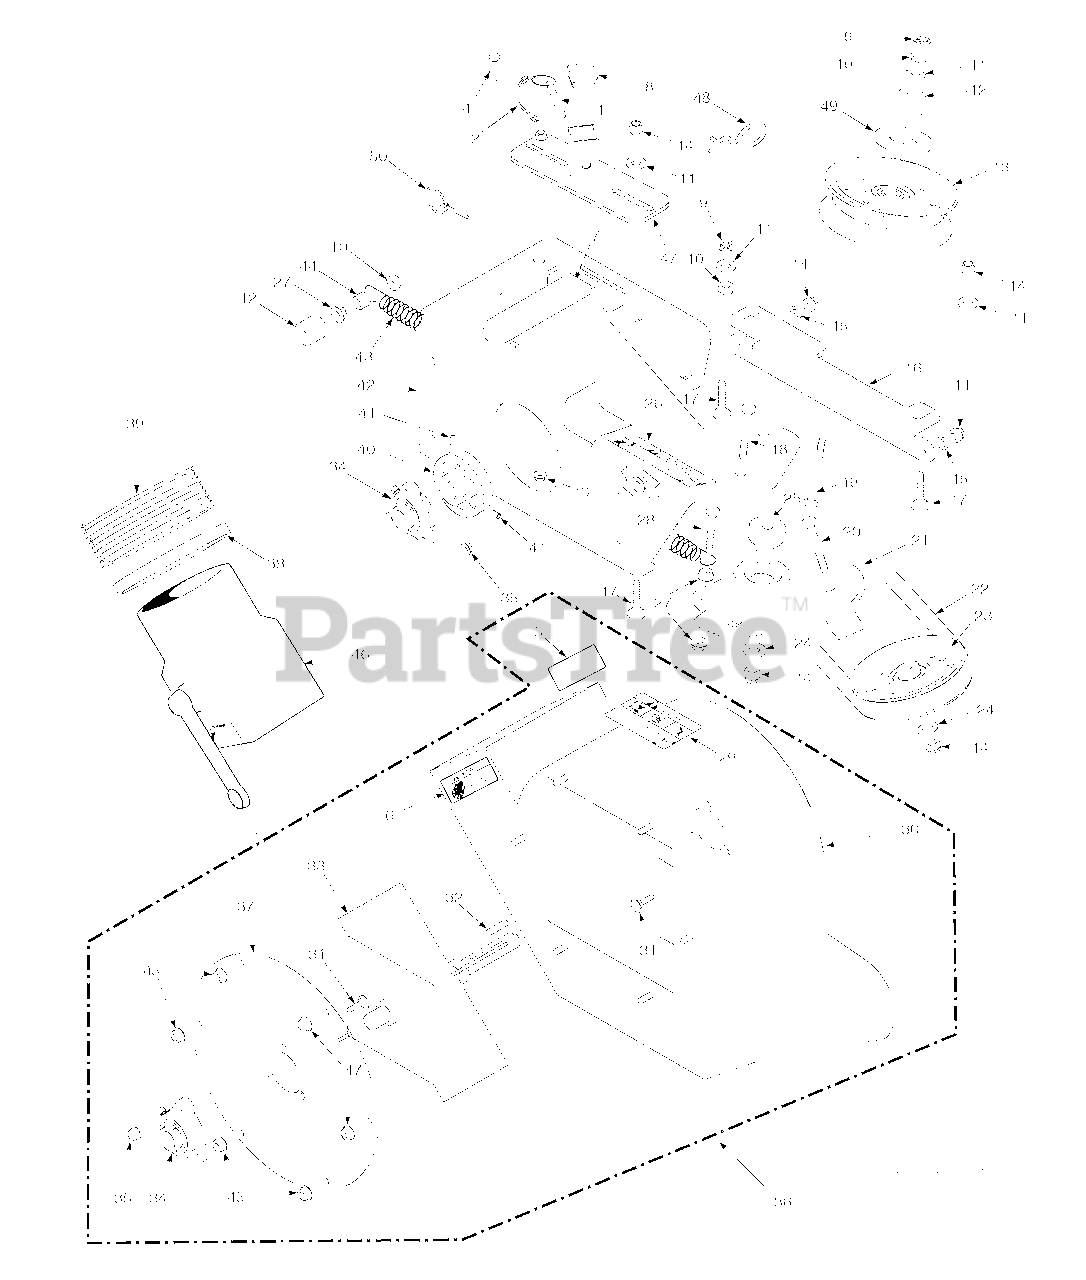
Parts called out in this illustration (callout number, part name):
1	Pin, Ring 2-1/4" Long
2	Lanyard, Deck Height Pin
3	Nut, Serr. Flange 1/4-20
4	Bolt, Hex Head 1/4-20 x 1-1/4"
5	Decal, Blower
6	Decal, Rotating Blower
7	Grip, Blower Lever
8	Cap, Square
9	Nut, Push On 3/8 Thread
10	Lock Nut, 3/8-16
11	Flatwasher, 3/8-.391 x .938 x .105
12	Spacer
13	Pulley, Idler 3-1/2" Dia. - 52"
13	Pulley, Idler 4" Dia. - 61"
14	Nut, Elastic Stop 3/8-16
15	Lockwasher, 3/8-16
16	Plate, Catcher Mounting
17	Bolt, Carr. 3/8-16 x 1-1/2"
18	Bolt, Hex Head 3/8-16 x 3" - 52"
19	Bolt, Hex Head 3/8-16 x 3-1/2"
20	Bolt, Hex Head 3/8-16 x 1-3/4"
21	Idler Arm Assembly - 61"
22	Belt, GC-STT-61V
23	Pulley, 3-1/2" O.D., GC-STC
24	Washer, 3/8 Hardened
25	Pivot, Idler - 61"
26	Decal, Belt Cover
27	Nut, Serr. Flange 3/8-16
28	Bolt, Hex Head 3/8-16 x 1-1/2 Gr. 8
29	Decal, Danger
30	Blower Housing Weldment w/Decals
31	Bolt, Carr. 5/16-18 x 3/4" Gr. 5
32	Key, 1/4 x 1/4 x 1-1/2"
33	Fan Weldment
34	Bearing Assembly
35	Nut, Elastic Stop 5/16-18
36	Blower Housing Assembly, GC-STT
37	Cover, Blower Housing
38	Clamp, 8-5/8" Max Dia.
39	Hose, 8.00" Dia. x 60.50" Long
40	Pulley, 4-3/4" O.D. - 1" Bore
41	Set Screw, 5/16-18 x 3/8"
42	Frame, Blower Mount
43	Spring, Main Drive
44	Spacer
45	Nut, Serr. Flange 5/16-18
46	Adapter w/Strap
47	Receiver Weldment, Mount Post - 61"
48	Hair Pin Cotter, .177 x 3-1/4"
49	Dust Shield
50	Quick Pin, 5/16" Dia.
